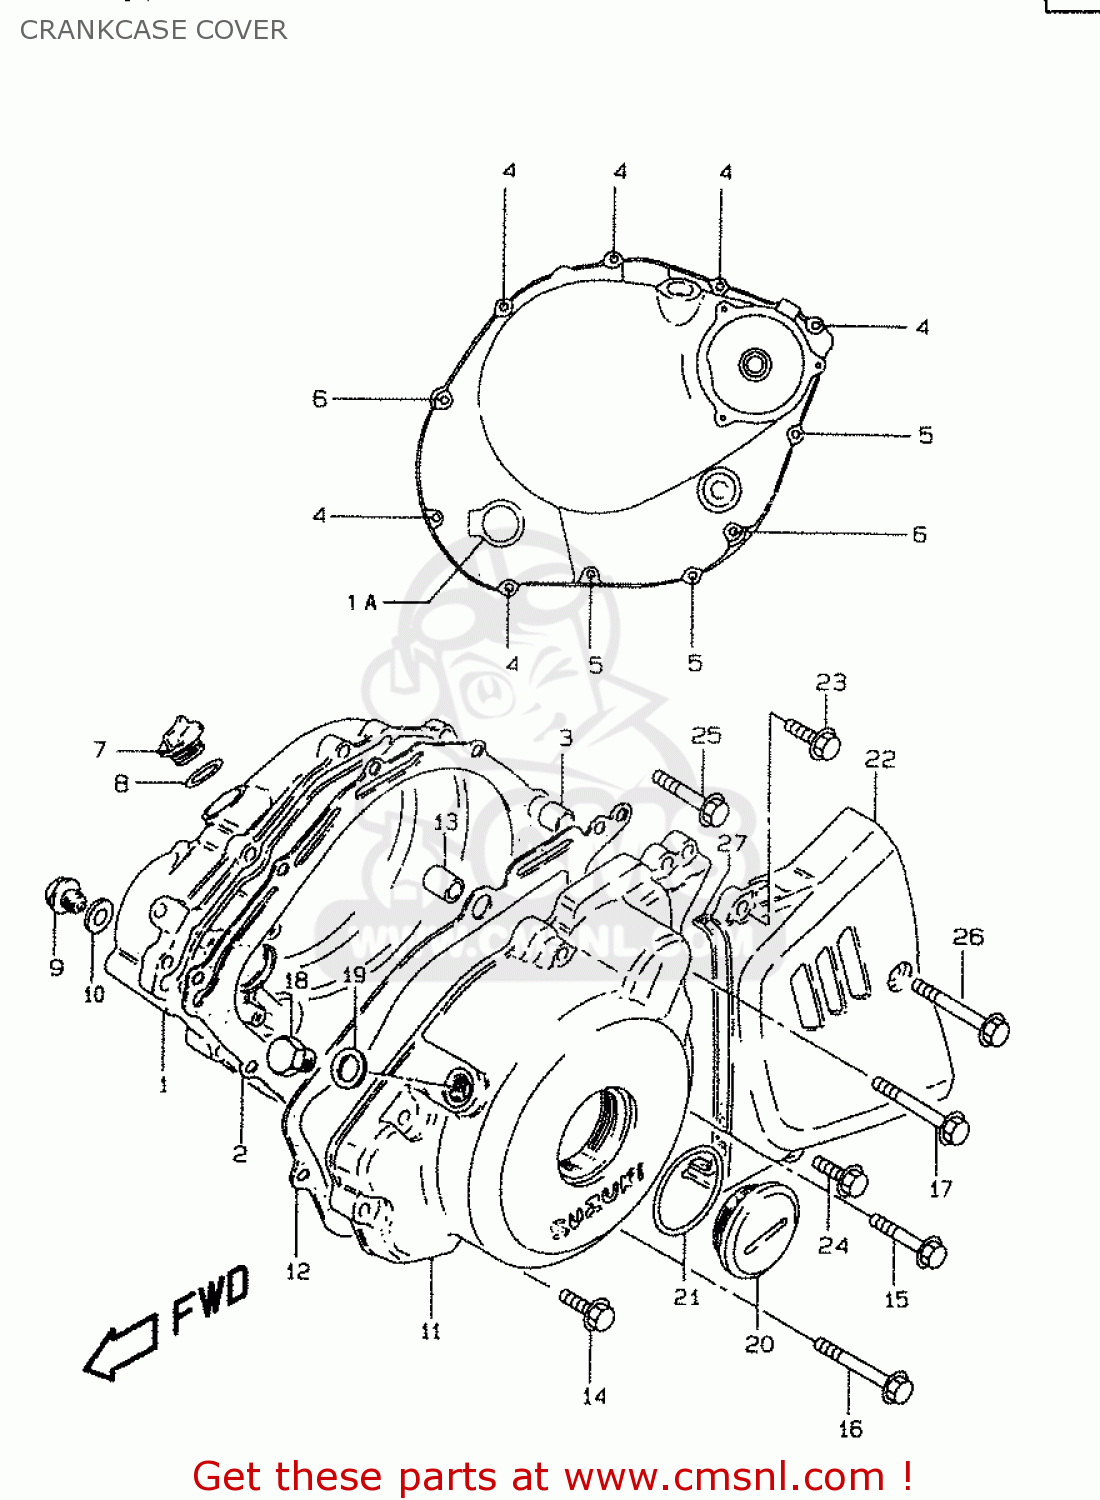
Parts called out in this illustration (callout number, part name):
1	COVER,CLUTCH
1A	LENS,OIL LEVEL CHECK
2	GASKET,CLUTCH COVER (NAS)
3	PIN
4	BOLT
5	BOLT
6	BOLT
7	PLUG(20X10)
8	O RING(D:3.1,ID:16.8)
9	PLUG(14X12)
10	GASKET(13.8X18.8X4.8) (NAS)
11	COVER,MAGNETO
12	GASKET,MAGNETO COVER (NAS)
13	PIN
14	BOLT
15	BOLT
16	BOLT
17	BOLT
18	PLUG,12X9
19	GASKET(12.1X16.2X3.7) (NAS)
20	PLUG,36X10
21	O RING(D:3.1,ID:32.7)
22	COVER,ENGINE SPROCKET
23	BOLT
24	BOLT
25	BOLT
26	BOLT
27	DAMPER,ENGINE SPROCKET COVER
